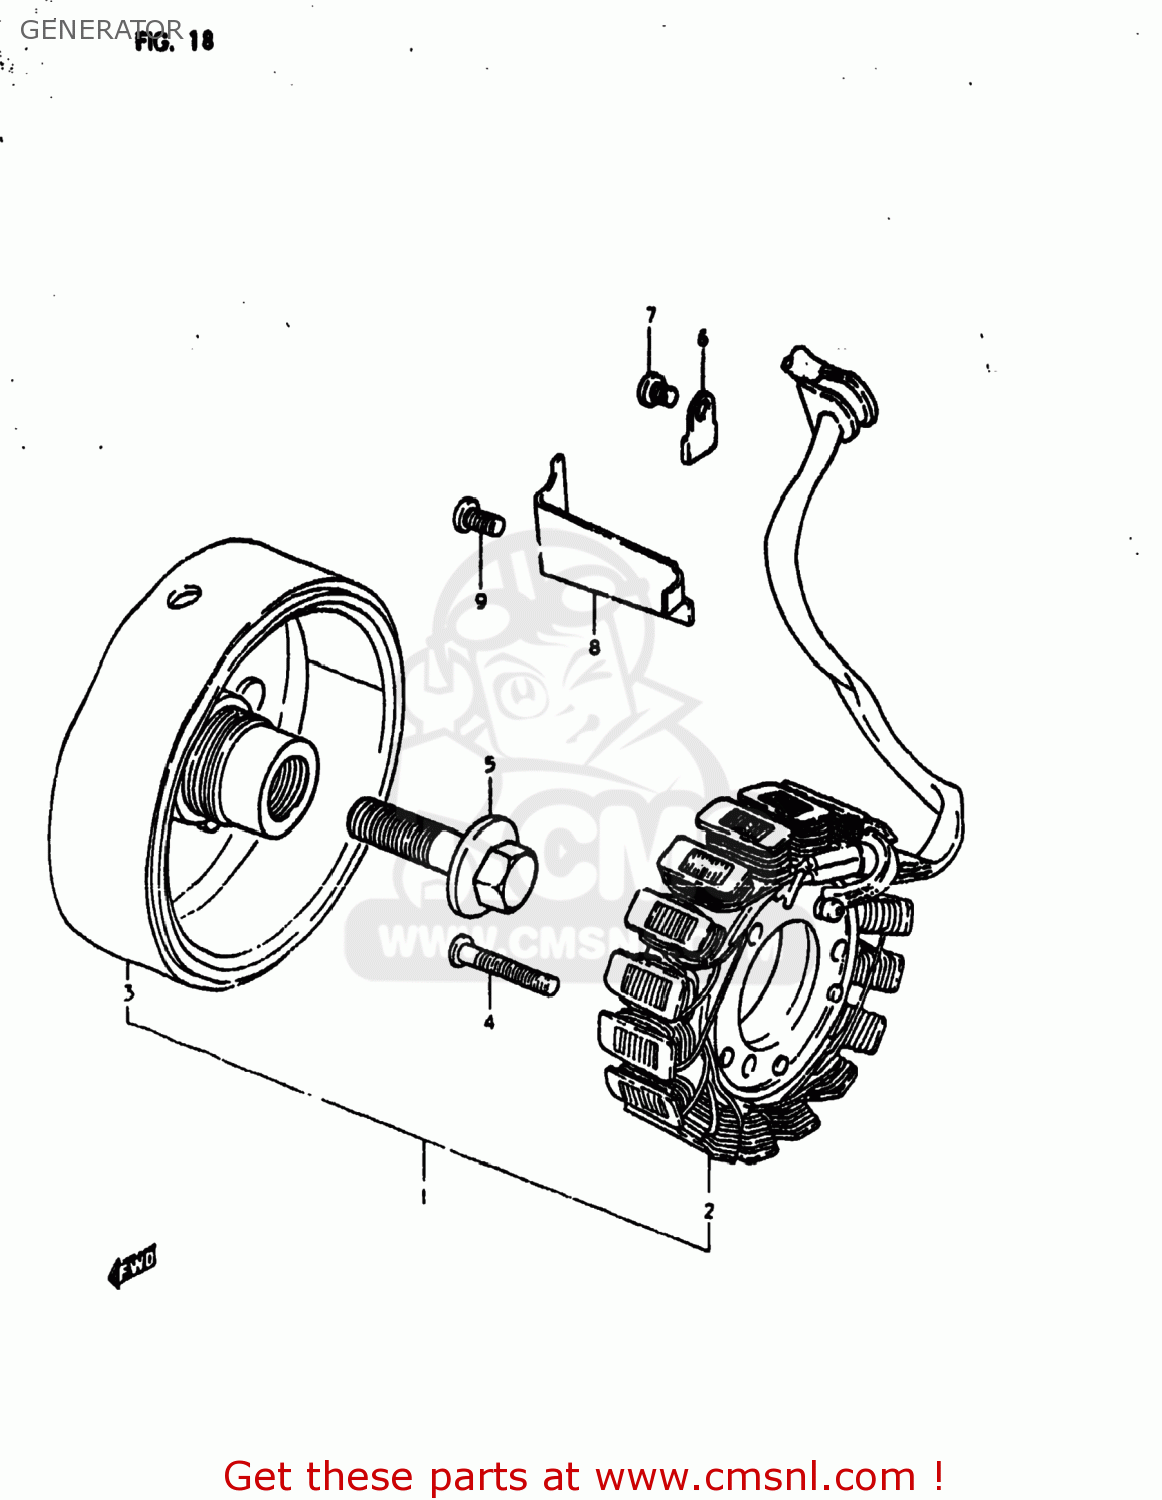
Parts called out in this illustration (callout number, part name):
1	GENERATOR ASSEMBLY
2	STATOR ASSEMBLY
3	ROTOR ASSEMBLY
4	SCREW 6X30
5	BOLT
6	CLAMP,GENERATOR LEAD WIRE
7	SCREW
8	CLAMP,GENERATOR LEAD WIRE
9	SCREW
